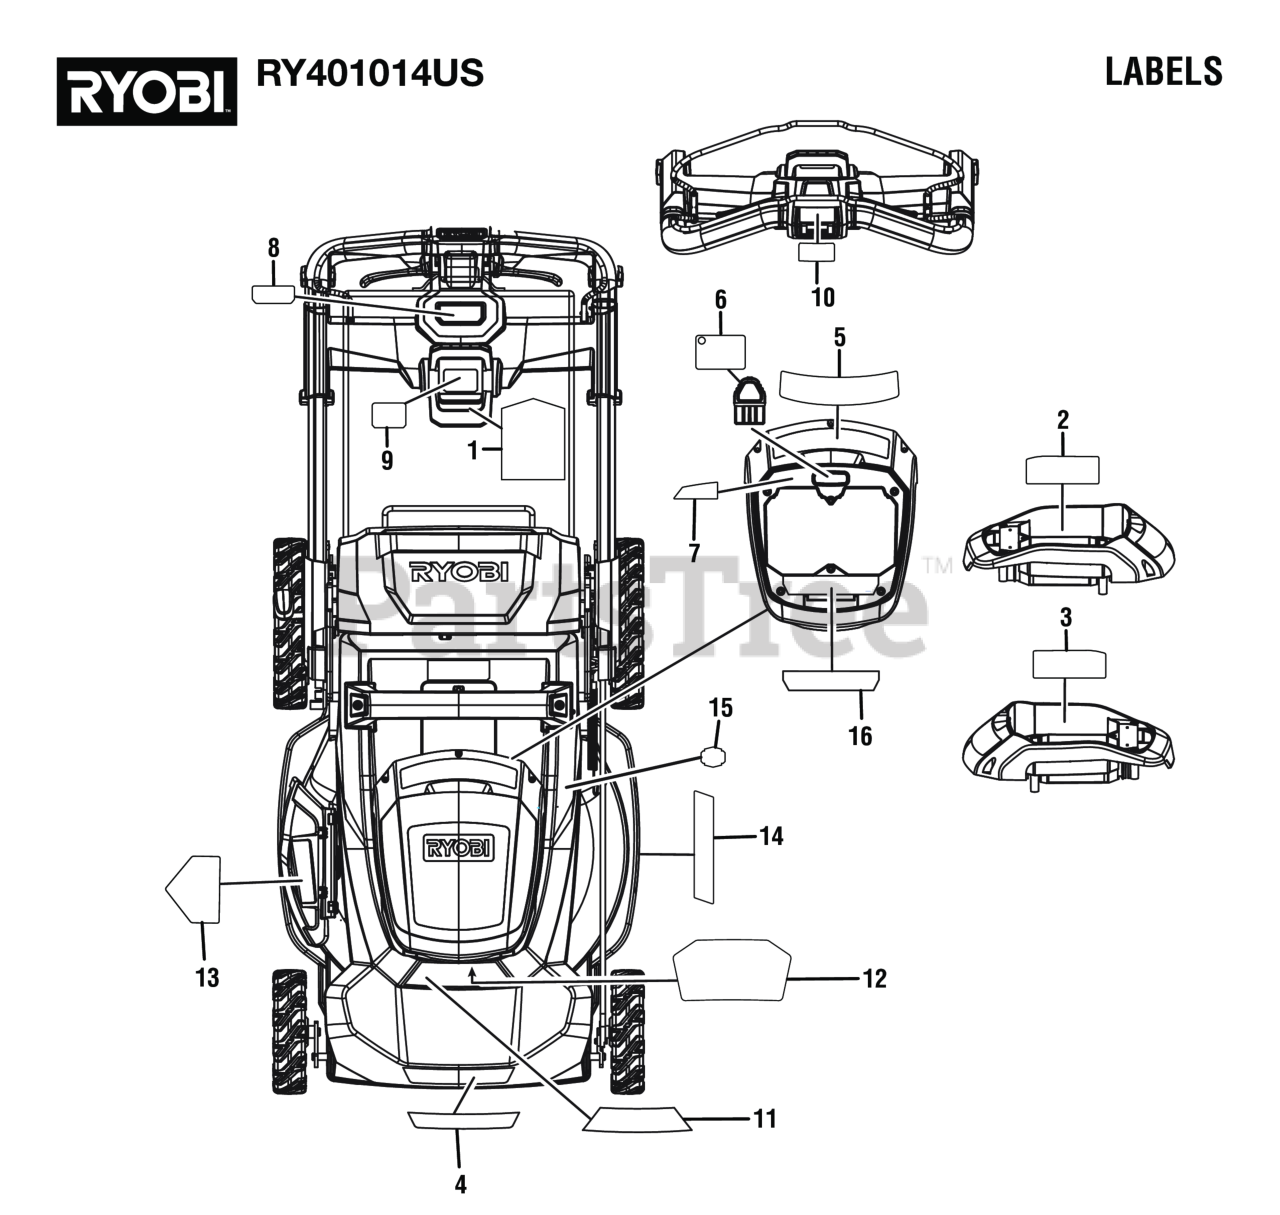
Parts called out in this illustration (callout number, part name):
1	Folding Instructions Hangtag
2	Start Key Warnings Label
3	Spanish Danger Label
4	Self-Propelled Label
5	Main Danger Label (EN/FR)
6	Start Key Battery Port Callout Hangtag
7	QR Code Label
8	RYOBI Logo Label
9	ONE FOLD Logo Label
10	Instructions Label
11	3-in-1 Cut Label
12	40V HP BRUSHLESS Logo Label
13	Danger Label (No Hands/Feet)
14	Right Side Label
15	Made in the USA Label
16	Battery Wet Conditions/Data Label
